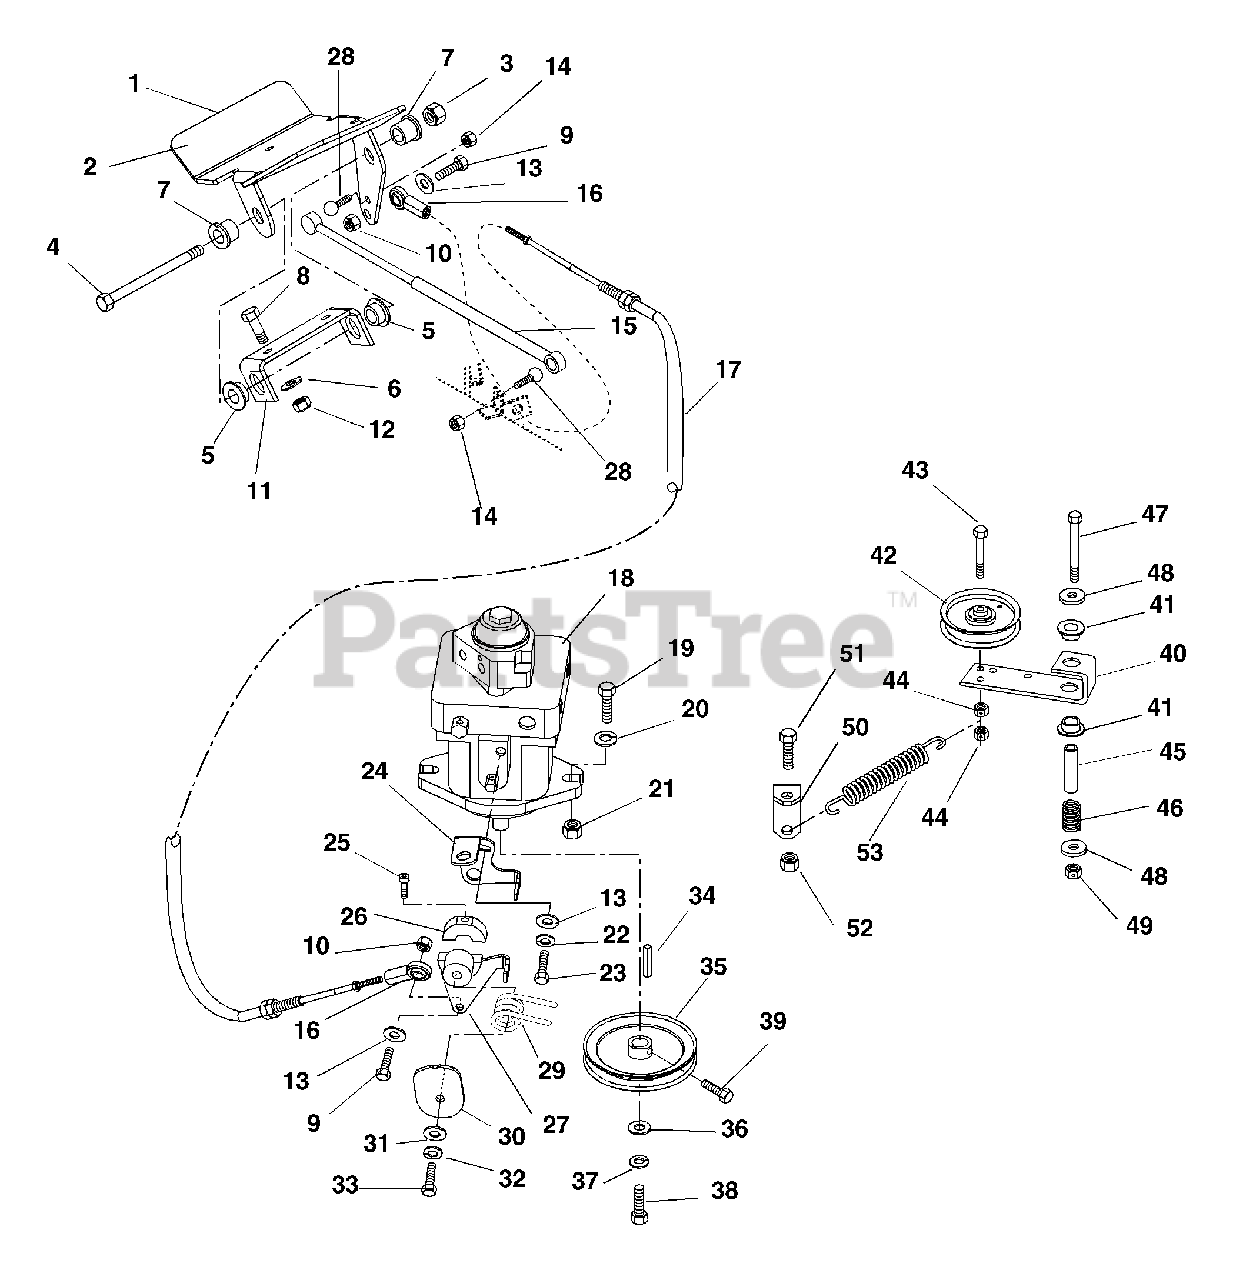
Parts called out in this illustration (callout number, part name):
1	Pedal, Direction Control
2	Pad, Foot Clutch Pedal
3	Nut-Locking-Center .50-13
4	Bolt-Hex .50-13 x 6.50 Grade 5
5	Bushing, Flange-Nylon .762 x 1.00 x .58 x 1.48
6	Washer-Flat-Steel .56 x 1.38 x .109
7	Bushing, Flange-Nylon .515 x .75 x .745 x 1.00
8	Bolt, Hex .38-16 x .75 Grade 5
9	Bolt-Hex .25-20 x 1.00 Grade 5
10	Nut-Locking-Nylon .25-20
11	Bracket, Control Pedal
12	Nut-Locking-Nylon .38-16
13	Washer-Flat-Steel .28 x .62 x .065
14	Nut-Locking-Center .31-18
15	Dampener Control
16	Rod End, Female .25-28
17	Cable, Forward-Reverse Control
18	Pump
19	Bolt-Hex .50-13 x 1.50 Grade 5
20	Washer-Flat-Steel .531 x 1.06 x .095
21	Nut-Locking-Nylon .50-13
22	Washer-Locking-External 262 x .502 x .026
23	Bolt-Hex .25-20 x .75 Grade 5
24	Arm, Neutral Return
25	Screw-Socket Head M6 x 1.00 x 35mm
26	Hub, Pump Neutral
27	Weldment, Pump Neutral
28	Stud, Ball
29	Spring-Torsion .156 x 1.275 x .77
30	Weldment, Pump Neutral
31	Washer-Flat-Steel .344 x .688 x .065
32	Washer-Locking .31 x .078 Regular
33	Bolt-Hex .31-24 x .75 Grade 5
34	Key-Straight 5mm x 25mm x 5mm
35	Sheave, Pump
36	Washer, Flat-Steel .281 x 1.00 x .048
37	Washer-Locking .25 x .062 Regular
38	Bolt-Hex M6 x 1.0 x 12
39	Bolt-Hex .25-20 x .50 Grade 5
40	Arm, Idler Pivot
41	Bushing-Flange Nylon .762 x 1.00 x .58 x 1.48
42	Idler-V 4.00 x .38
43	Bolt-Hex .38-16 x 2.25 Grade 5
44	Nut-Locking-Center .38-16
45	Spacer, Steel .56 x .75 x 2.44
46	Spring-Compression .09 x .80 x 1.00
47	Bolt-Hex .50-13 x 3.50 Grade 5
48	Washer Flat Steel .53 x 1.25 x .100
49	Nut-Locking-Nylon .50-13
50	Anchor, Spring Idler
51	Bolt-Hex .38-16 x 1.00 Grade 5
52	Nut-Locking-Nylon .38-16
53	Spring, Extension
